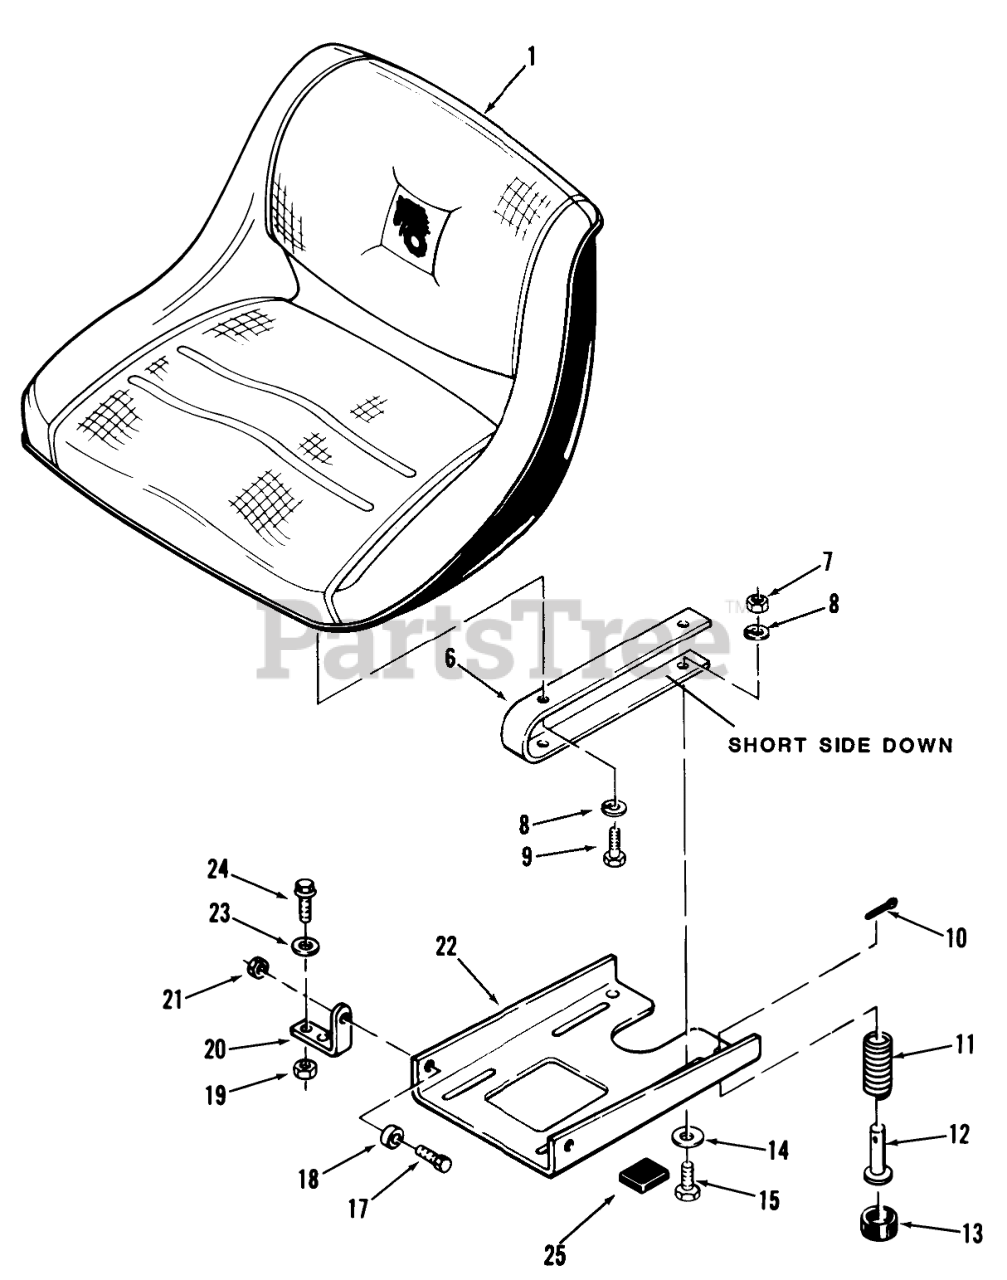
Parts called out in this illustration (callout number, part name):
1	Seat
6	Spring
7	Nut
8	Lockwasher
9	Bolt
10	Cotter Pin
11	SPRING
14	WASHER 5/16 SAE
15	HHCS
17	HHCS
18	BUSHING
19	Nut
20	BRACKET-PIVOT
21	Nut
22	Pivot Plate
23	WASHER 5/16 SAE
24	Bolt
24	HHCS
25	BUMPER
